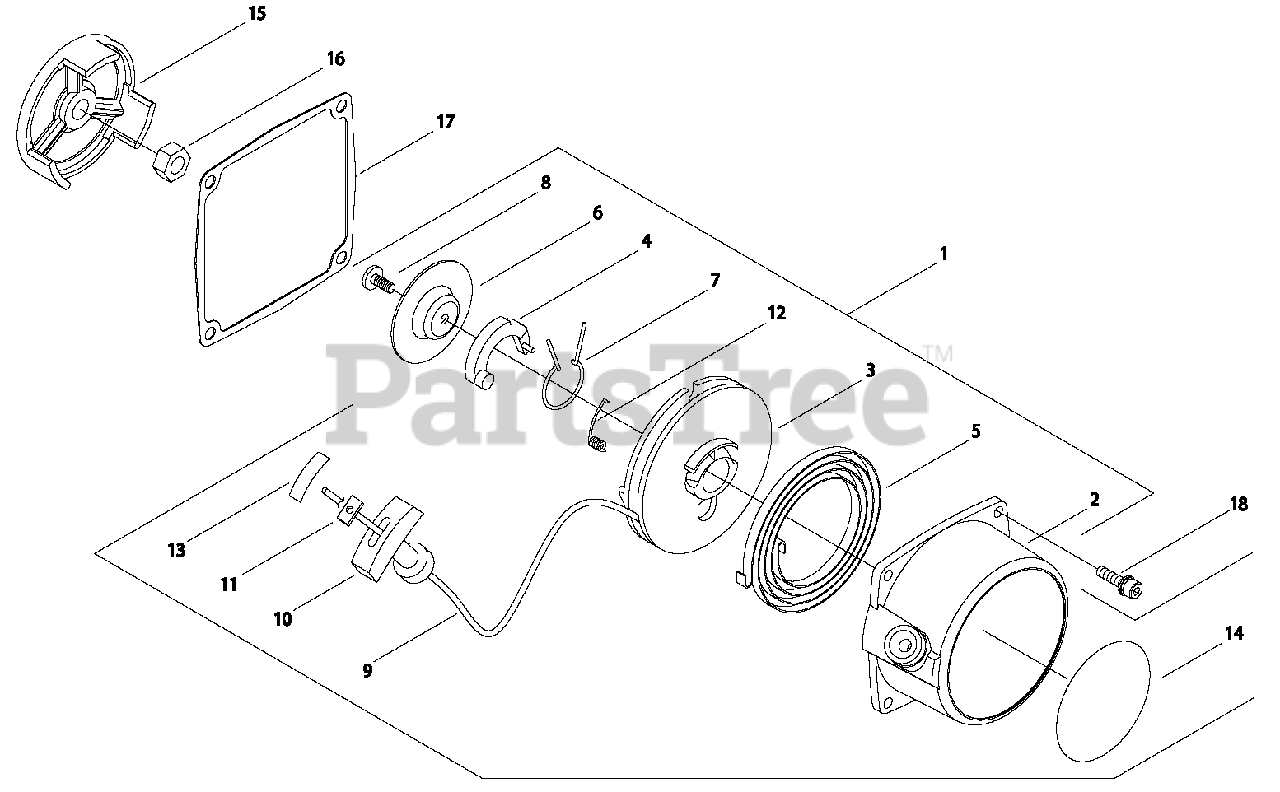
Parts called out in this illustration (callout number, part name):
1	STARTER ASSY
2	CASE, STARTER
3	REEL, ROPE
4	PAWL, STARTER
5	SPRING, REWIND
6	PLATE, STARTER
7	SPRING, FRICTION
8	SCREW
9	ROPE, STARTER
10	GRIP, STARTER
11	RETAINER, ROPE
12	SPRING, RETURN
13	TAPE, ADHESIVE
14	LABEL - MODEL
15	PAWL, STARTER
16	NUT - 8
17	GASKET, STARTER
18	SCREW - 4X16
